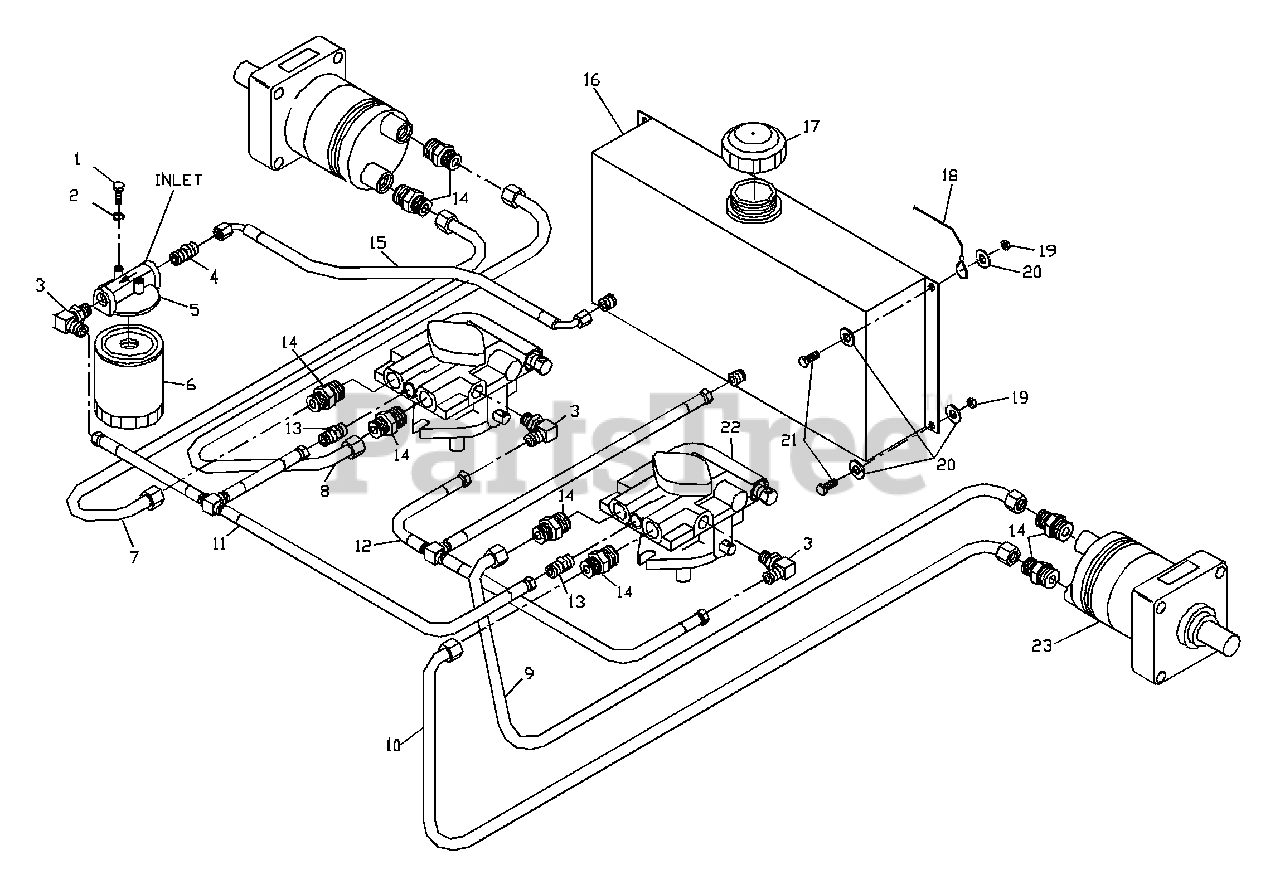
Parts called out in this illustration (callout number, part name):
1	HCS 1/4C X 5/8
2	1/4" LOCKWASHER
3	F6801-6-6-0 90 DEG. ELBOW
4	F6400-6-6-0 STRAIGHT FITTING
5	FILTER HEAD
7	RIGHT OUTSIDE TUBE
8	RIGHT INSIDE TUBE
9	LEFT INSIDE TUBE
10	LEFT OUTSIDE TUBE
11	SUCTION TEE ASSEMBLY
12	RETURN TEE ASSEMBLY
13	F6400-6-4-0 STRAIGHT FITTING
14	F6400-8-8-0 STRAIGHT FITTING
16	TANK, HYDRAULIC
17	HYDRAULIC CAP
18	SEAT LANYARD
19	NUT 1/4C CENTERLOCK
20	WASHER 1/4 FLAT
21	HCS 1/4C X 1
23	WHEEL MOTOR
